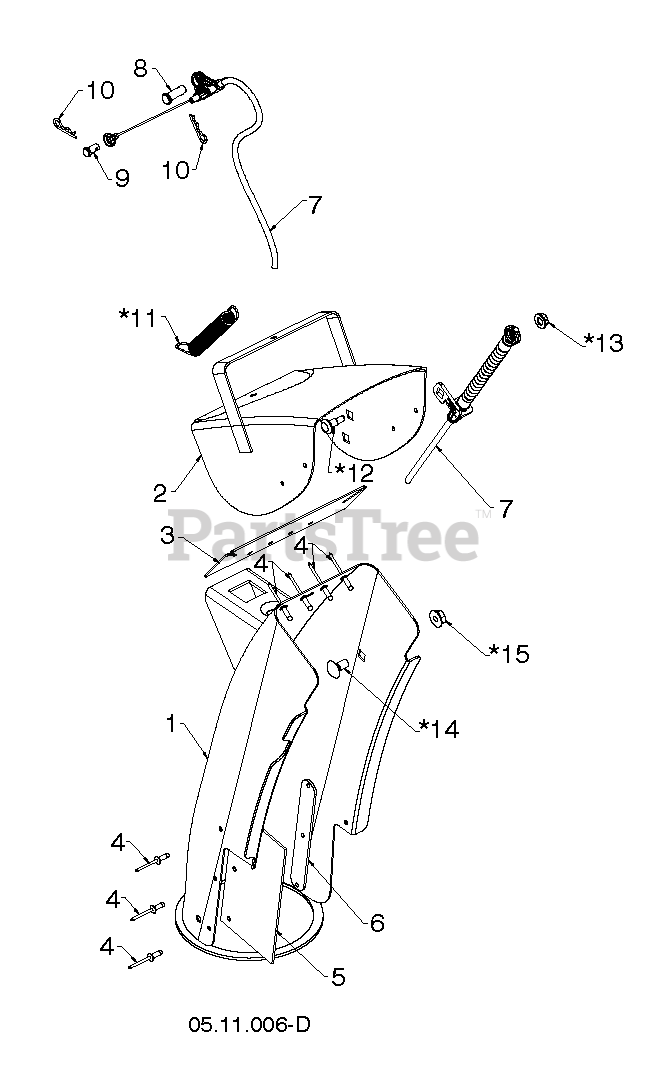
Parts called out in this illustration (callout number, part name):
1	DEFLECTOR, ASSY.
7	Deflector Chute Control Cable
8	Clevis Pin, 5/16 X .875
9	Clevis Pin, .25 X .31
11	SPRING.DEFLECTOR.REM.CHUTE
12	Shoulder Bolt, 1/4
13	Flange Hex Lock Nut, 1/4-20 Large
14	Carriage Bolt, 5/16-18 X 5/8 Black
15	LOCKNUT-FLANGE 5/16-18
